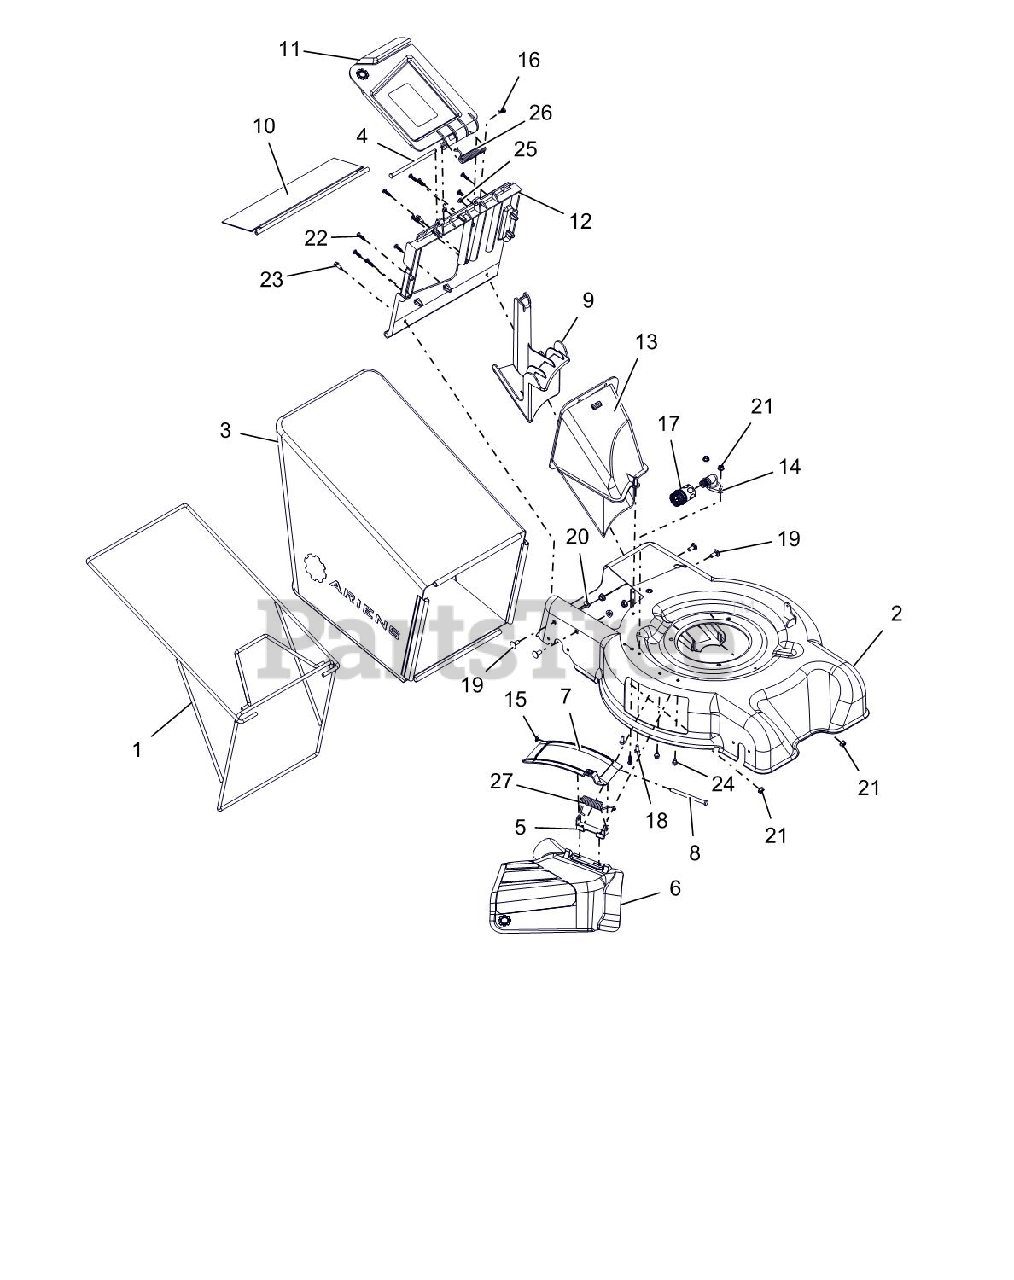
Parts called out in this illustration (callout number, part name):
1	FRAME, BAGGER
2	WLDMT, ARIENS WP DECK
3	BAGGER-GRASS-ARIENS
4	PIN, 5/16 X 5.80"
5	BRKT, HINGE LM
6	CHUTE, SIDE DISCHARGE - LM
7	COVER, SIDE DISCHARGE - LM
8	PIN, HINGE
9	PLUG, MULCH
10	GUARD, REAR DECK
11	REAR DOOR W/ SAFETY DECAL
12	HANGER, REAR BAG
13	CHUTE, REAR DISCHARGE LM
14	ASSY, WASHOUT PORT W/ O-RING
15	NUT-PUSH .312
16	PIN-HAIR INT .08X.18X1.18 YWZC
17	COUPLING, QUICK DISCONNECT
18	BLT-HEX .25-20X.63 GR5 YWZC
19	@BLT-RDHDSQNK .31-18X.75 G5YZ
20	@NUT-LK-TOP-FLG .31-18 YWZC
21	@NUT-LK-TOP-FLG .25-20 YWZC
22	SCR-TAP 12-14X.75PLSTITE @BLZC
23	@SCR-TAP .25-20X.62 HWH TR YWZ
24	@SCR-TAP .25-20X.37 HWH YWZ TR
25	PLUG,5/16 HOLE,.125 MATL PLSTC
26	SG-TORS .120X.68X3.09
27	SPRING, SIDE DISCHARGE DOOR
